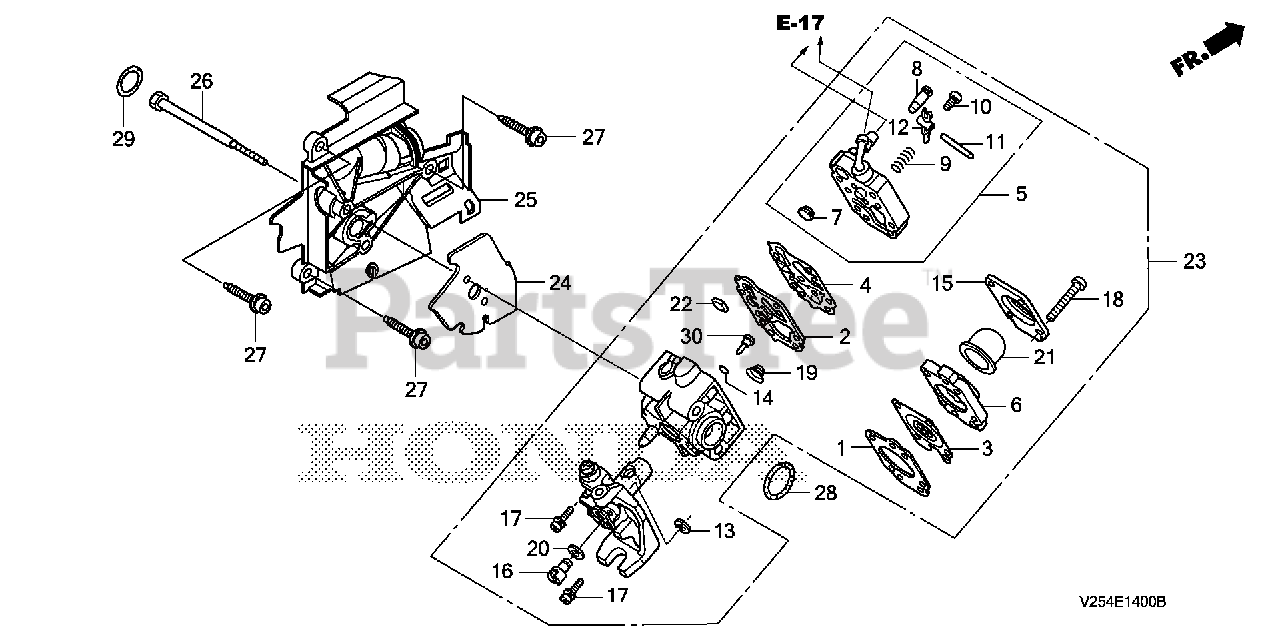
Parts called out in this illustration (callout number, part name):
1	GASKET, METERING DIAPHRAGM
2	GASKET, PUMP (CARBURETOR NO.)
3	DIAPHRAGM ASSY., METERING
4	DIAPHRAGM, PUMP
5	BODY ASSY., PUMP (CARBURETOR NO.)
6	BODY ASSY., AIR PURGE
7	SCREEN, INLET (CARBURETOR NO.)
8	VALVE, INLET NEEDLE
9	SPRING, METERING LEVER
10	SCREW, METERING LEVER PIN
11	PIN, METERING LEVER
12	LEVER, METERING
13	RING, RETAINING
15	COVER, PRIMER PUMP
17	SCREW, THROTTLE COLLAR
18	SCREW, PUMP COVER
19	SPRING, PUMP
21	PUMP, PRIMER
22	FILTER, FUEL INLET (CARBURETOR NO.)
23	CARBURETOR ASSY. (WYB 46)
24	GASKET, CARBURETOR
26	BOLT (5X53)
27	BOLT, SOCKET (5X16)
28	O-RING (14.8X2.4)
29	O-RING (12.3X2.4) (CARBURETOR NO.)
30	JET (#33) (CARBURETOR NO.)
30	JET (#34) (CARBURETOR NO.)
30	JET (#35) (CARBURETOR NO.)
